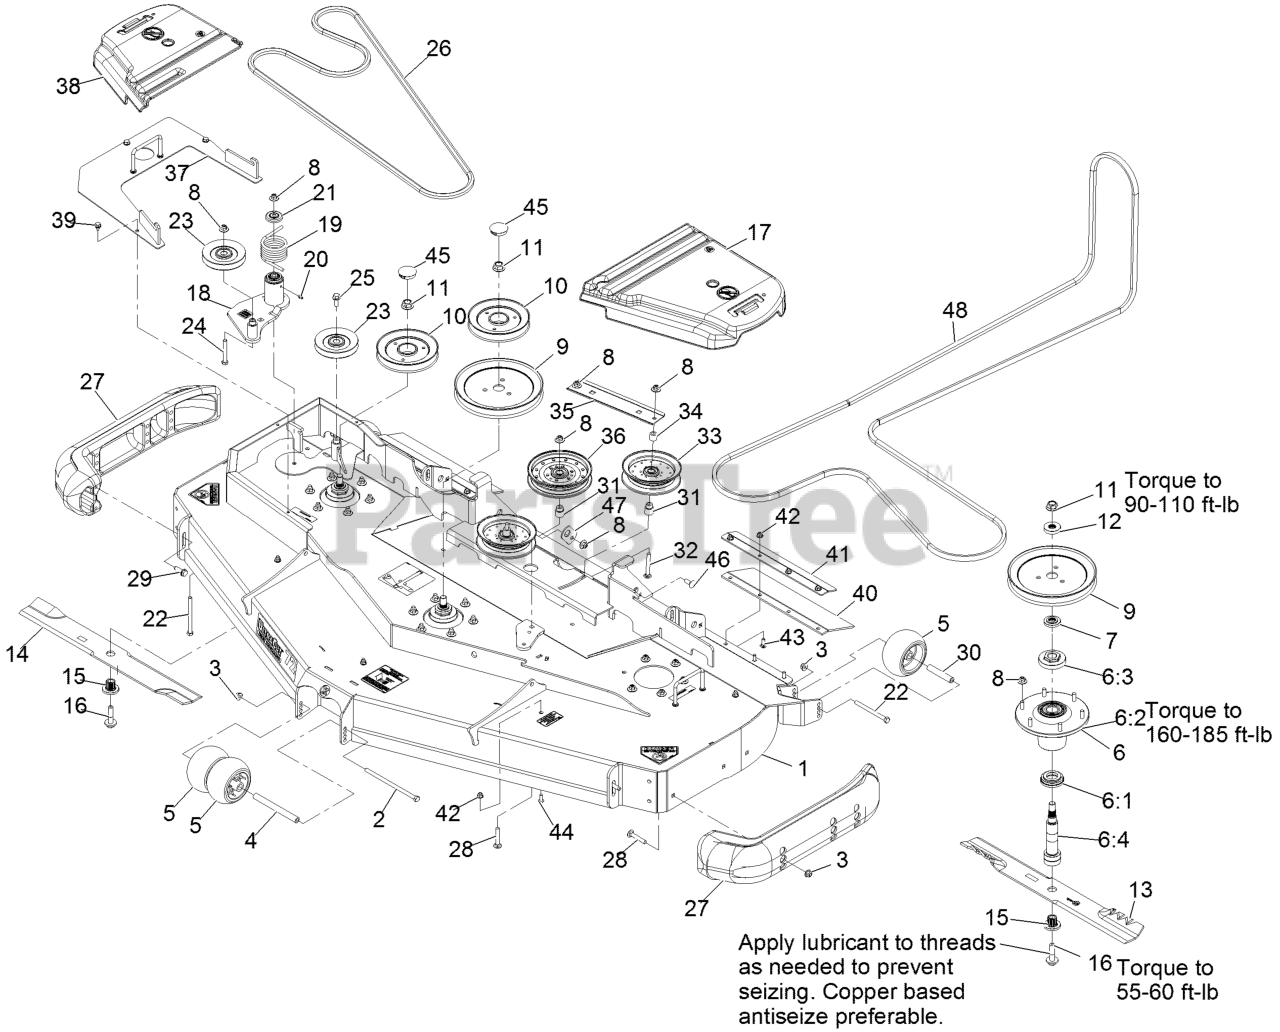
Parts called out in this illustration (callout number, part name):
1	DECK-RD72, W/DECALS
2	SCREW-HH
3	NUT-HF, NI
4	SPACER-WHEEL
5	ROLLER-SCALP, ANTI
6	ASM,SPINDLE HOUSING
6:1	GUARD,BOTTOM
6:2	ASM,CUTTER HOUSING
6:3	NUT, SPINDLE 7/8-14
6:4	SPINDLE,DOUBLE SPLINE
7	SPACER,SPLINED STEPPED
8	Nut-Nyloc 3/8-16 Flg
9	SHEAVE,BLADE DRIVE 9.00
10	SHEAVE-RD, REVERSE DRIVE
11	NUT-FLANGE, CENTERLOCK
12	SPACER,SPLINED
15	BUSHING,SPLINED
16	SCREW,SEMS 1/2-20 X 2.19
17	COVER-BELT, LH
18	ASM-DECK IDLER
19	SPRING-TORSION
20	FITTING-GREASE
21	GUARD-TOP
22	SCREW-HH
23	SHEAVE-4.14 A-SEC EOD
24	SCREW-HH
25	SCREW-HHF
27	SKID-BUMPER, DECK
28	Bolt-Carriage 3/8-16 X 2 1/4
29	SCREW-HWHTF
30	TUBE-SPANNER
31	BUSHING-IDLER
32	SCREW-CARR
35	GUIDE-RD BELT
37	COVER-RD72 REVERSE DRIVE
38	COVER-BELT, RH
40	GUARD-TIRE RD72
41	SUPPORT-OUTER FLAP RD72
42	NUT-HF, NI
43	SCREW-CARR
44	SCREW-HSBH
45	PLUG,BLACK NYLON 1.75
46	BOLT-CARR
47	PLATE,DECK STRUT
48	BELT-V
